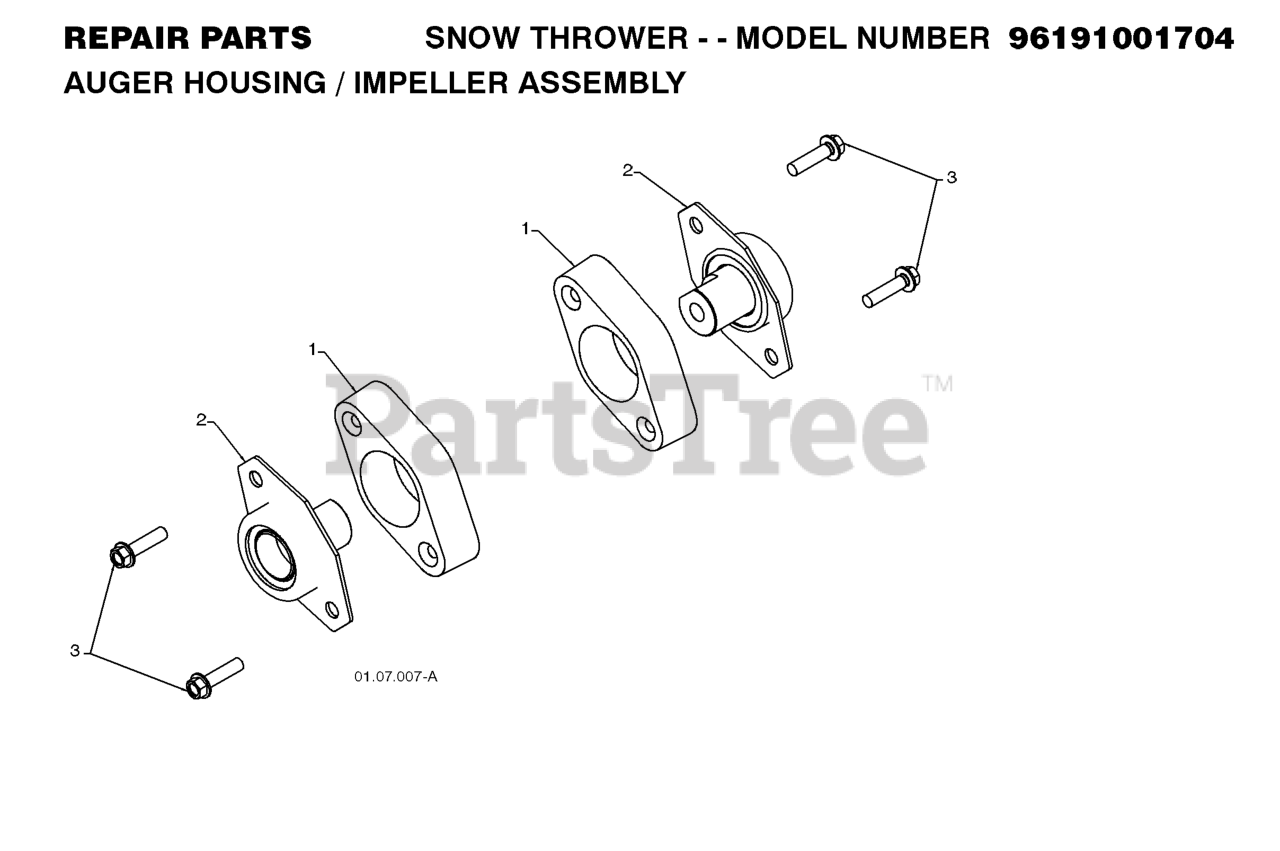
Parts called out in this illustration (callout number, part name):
1	BEARING RETAINER, PLASTIC
2	BEARING.BALL.AUGER
3	SCREW, HEX HD 5/16X1
